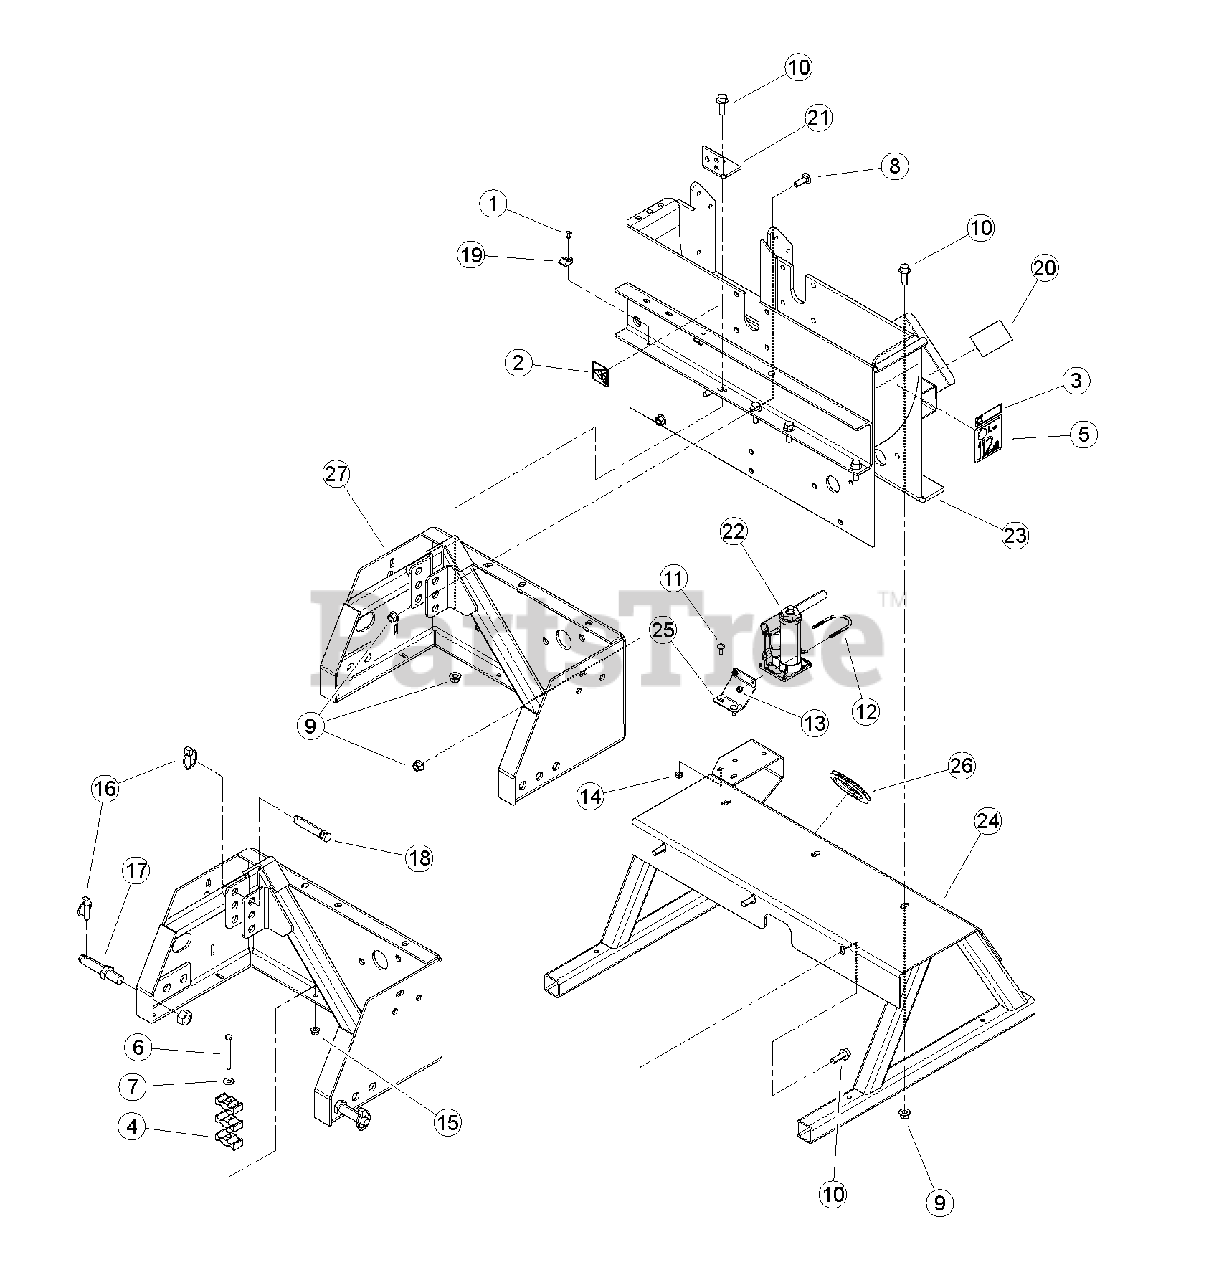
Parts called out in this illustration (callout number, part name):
1	RIVET, 1/4 X 3/4 ST POP
2	DECAL, SHIELD DANGER ISO
3	DECAL,CH9540 INFORMATION (CE COMPLIANT ONLY)
4	CLAMP, PLASTIC HOSE
5	DECAL, 112 DB (CE COMPLIANT ONLY)
6	BOLT, 3/8 X 3-1/2" HEXHD GR5 ZP
7	WASHER, 3/8" FLAT ZP
8	BOLT, 1/2 X 1-1/2" GR5 CRG ZP
9	NUT, 1/2-13 NYLOCK FLANGE
10	BOLT, 1/2-13 X 1-1/2 GR5 FLANGE NC
11	BOLT, 5/16 X 7/8" GR5 CRG NC ZP
12	U-BOLT, 1/4 X 1-1/2 PIPE
13	NUT, 1/4-20 NYLOCK-FLANGE
14	NUT, 5/16-18 NYLOCK-FLANGE
15	NUT, 3/8-16 NYLOCK FLANGE
16	PIN, 7/16 X 1-3/4 LYNCH
17	PIN, LIFT ARM 7/8 X 5" LG
18	PIN, TOP LINK 3/4 X 4-1/2" LG
19	CLAMP, CABLE MOUNT
20	DECAL, FEED SPEED
21	ANGLE, LOWER SHOCK
22	JACK, HYDRAULIC 2 TON
23	WELDMENT, CHIPPER BOTTOM
24	WELDMENT, PTO STAND
25	PLATE, JACK MOUNT
26	TRIM, SLOT EDGE COVER
27	WELDMENT, HITCH SUPPORT
